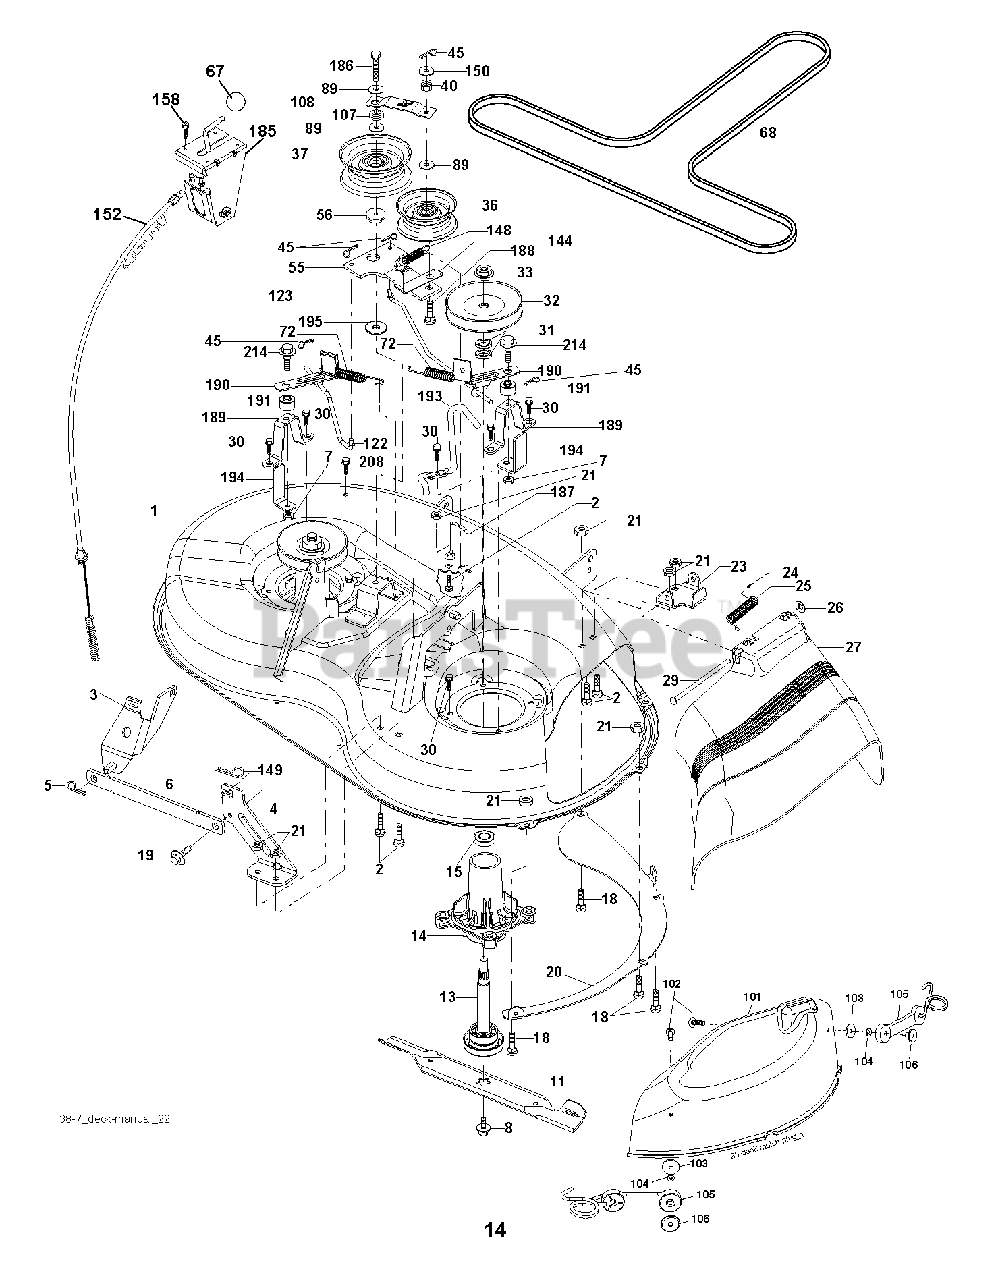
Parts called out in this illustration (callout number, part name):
1	DECK.WELDMENT.38"2005
2	BOLT
3	BRKT ASM SWAY BAR
4	BRACKET DECK SWAY BAR 38"/42"
5	RETAINER-SPRNG RB
6	BAR SWAY DECK
7	NUT.71038.31-18.HEX.NYLOCK
8	BOLT.WASHER.ASM.7/16-2
11	BLADE 38" PREMIUM
13	SHAFT.ASM.MDRL.N/GREASE.38
14	HOUSING MANDREL
18	BOLT
19	BOLT SHD 5/16-18
20	BAFFLE VORTEX
21	LOCKNUT
23	BRKT.DEFLECTOR.38"2005+
24	CAP-SLEEVE LT
25	SPRING.TORSION.DEFLECT
27	Deflector Shield, 38-7/97cm
29	ROD.HINGE
30	SCREW, WASHER HEAD
31	WASHER.SPACER.MANDREL
32	PULLEY MANDREL
33	NUT.FLANGE.LOCK.TOP
36	FLAT IDLER PULLEY
37	PULLEY.IDLER.FLAT.UNPLATED
40	LOCKNUT
45	RETAINER M
56	SPACER.RETAINER.MOWER
67	KNOB T (3/8 HOLE)
68	V-BELT.MOWER.38"2005+
72	SPRING.BRAKE.RETURN.38"
89	WASHER
106	WELDNUT
107	SPACER.IDLER.ARM
108	STIFFENER.IDLER.ARM
122	ROD, BRAKE LH LINK
123	LINK.BRAKE.38"RIGHT
148	IDLER RETURN SPRING
149	SPRING.RETAINER.YELLOW.ZINC
150	WASHER LT
158	SCREW
185	HEAD ASM. CABLE CLUTCH
186	SCREW.HXWSH.3/8
188	BOLT, CARRIAGE IDLER
189	STAND, BRAKE
190	ARM, BRAKE
191	SPACER, BRAKE
193	KEEPER BELT RH MANDREL
194	GUARD BRAKE
195	WASHER 12/32X2X10GA
208	SCREW 3/8-16X1/2
214	BOLT/WASHER ASM 5/16-18
